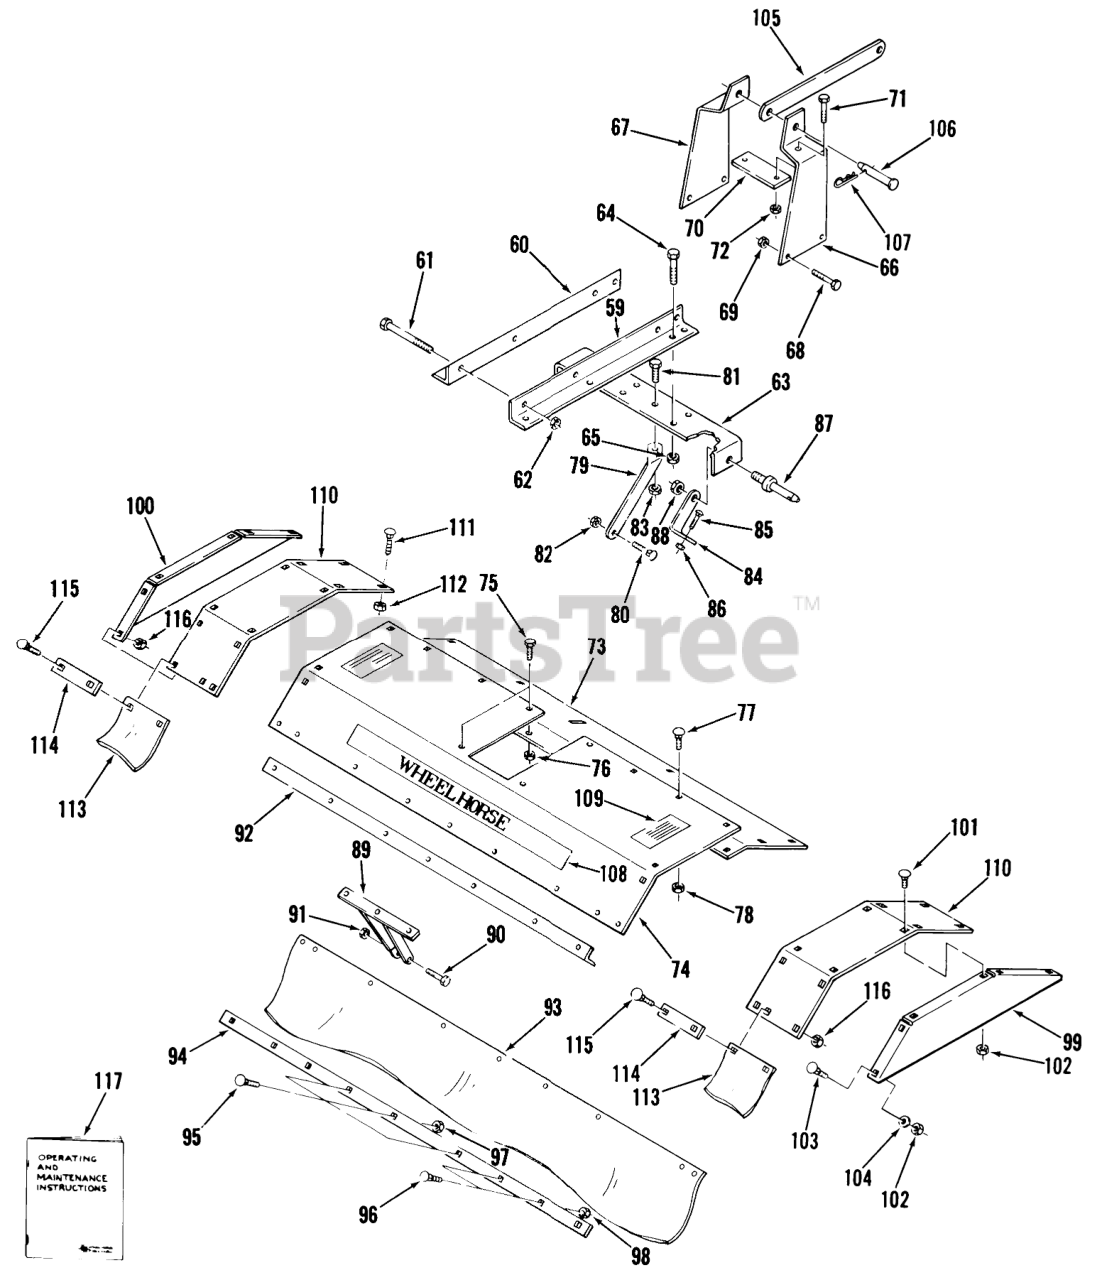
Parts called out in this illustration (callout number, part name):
59	R.H. Tiller Support Angle
60	L.H. Tiller Support Angle
61	Bolt 1/2-13 x 6 1/2
62	Nut
63	Lower Hitch Bar
64	Hhcs
65	Nut
66	R.H. Upper Hitch Plate
67	L.H. Upper Hitch Plate
68	Bolt
69	NUT
70	Strap
71	Bolt
72	Nut
73	Front Tine Shield
74	Rear Tine Shield
75	BOLT
76	NUT
77	Bolt
78	Nut
79	Front Brace
80	Bolt
81	Hhcs
82	NUT
83	Nut
84	Tine Shield Brace
85	Bolt
86	Nut
87	Lower Link Pin
89	Spring
90	Bolt
91	NUT
92	Tine Shield Angle
93	GUARD-REAR TINE
94	Strap
95	Bolt
96	Bolt-Carriage
97	NUT
98	Nut
99	R.H. Tine End Cover
100	L.H. Tine End Cover
101	Bolt
102	Nut
103	Bolt-Carriage
104	WASHER 5/16 SAE
105	LINK UPPER
106	PIN HITCH UPPER LINK
107	Hairpin
108	Decal
109	Caution Decal
110	Cover-Extension
111	Bolt
112	Nut
113	Tine Guard
114	Strap
115	Bolt-Carriage
116	Nut
117	Operating and Maintenance Instructions
